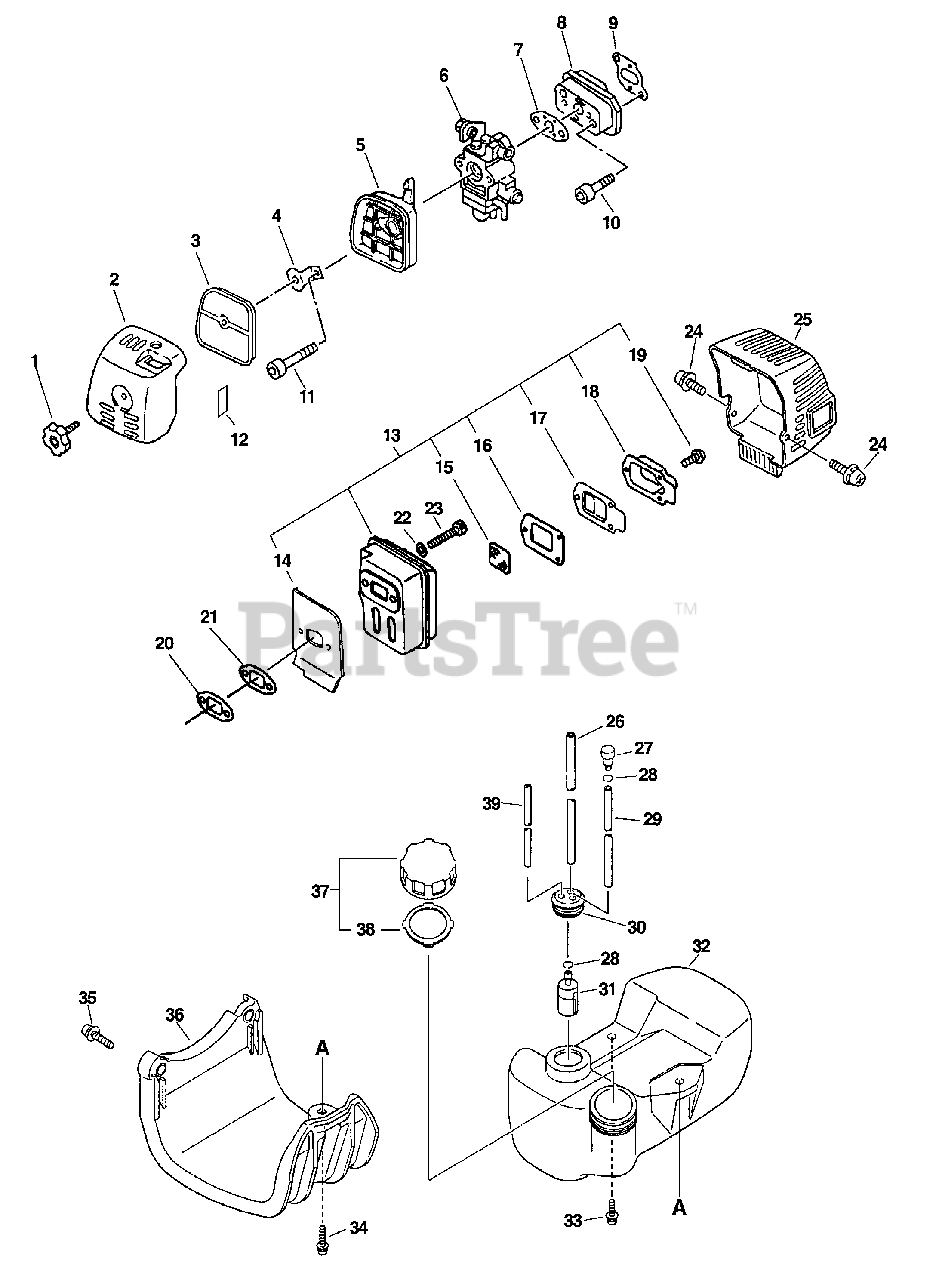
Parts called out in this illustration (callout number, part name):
1	THUMBSCREW
2	COVER, AIR FILTER
3	FILTER, AIR - HEAVY DUTY
4	PLATE, PREVENT
5	CASE, AIR FILTER
6	CARBURETOR WYJ-192
7	GASKET, INTAKE
8	INSULATOR, INTAKE
9	GASKET, INTAKE
10	SCREW - 5X25
11	SCREW - 5X55
12	LABEL - CHOKE
13	MUFFLER ASSY
14	SHIELD, EXHAUST
15	SCREEN, SPARK ARRESTOR
16	GASKET, EXHAUST
17	GASKET, EXHAUST - INNER
18	GUIDE, EXHAUST - OUTER
19	SCREW - 4X10
20	GASKET, EXHAUST
21	SPACER
22	WASHER - 5
23	SCREW - 5X55
24	SCREW - 5X12
25	COVER, EXHAUST
26	PIPE - 3X6X170 -- BLACK
27	VENT, FUEL TANK
28	CLIP - 6.5
29	PIPE - 3X6X100 -- BLACK
30	GROMMET
31	FILTER, FUEL
32	TANK, FUEL
33	SCREW - 5X16
34	SCREW - 5X20
35	SCREW - 5X22
36	GUARD, FUEL TANK
37	CAP ASSY
38	GASKET, CAP
39	PIPE - 3X6X60 -- CLEAR
